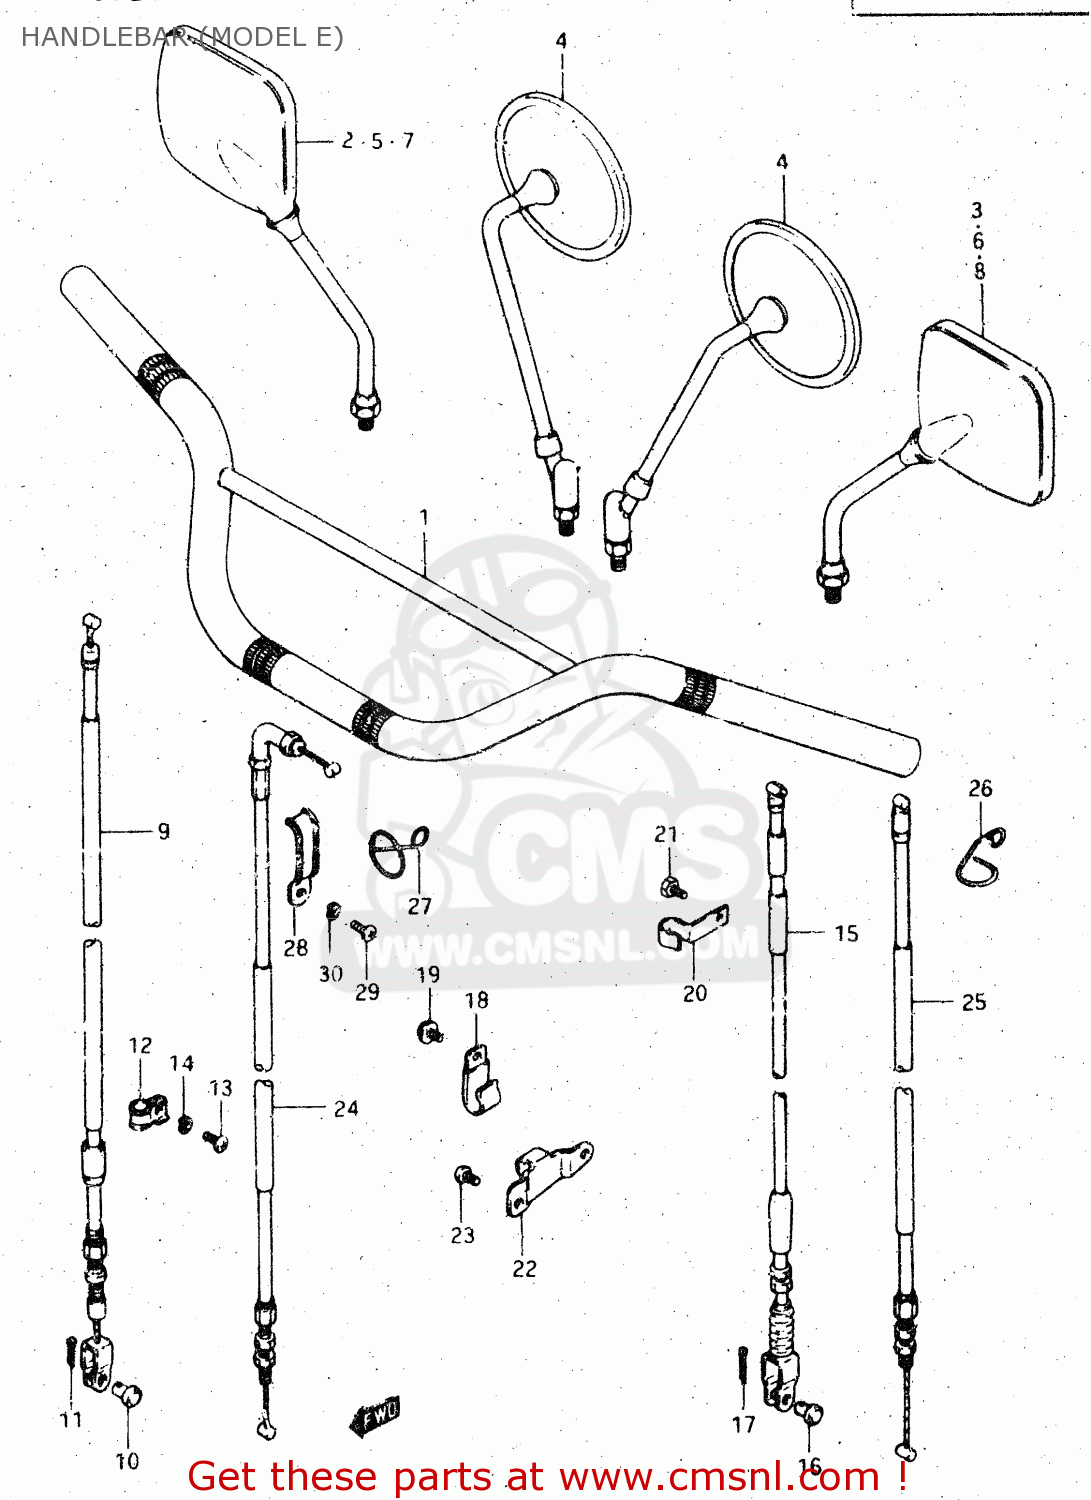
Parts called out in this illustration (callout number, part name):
1	HANDLEBAR (BLACK)
2	MIRROR ASSEMBLY,REAR VIEW
3	MIRROR ASSEMBLY,LEFT
4	MIRROR ASSY,RH
5	MIRROR ASSEMBLY,RIGHT
6	MIRROR ASSEMBLY,LEFT
7	MIRROR, REAR VIEW RH
8	MIRROR, REAR VIEW LH
9	CABLE ASSEMBLY,FRONT BRAKE
10	PIN(L:17.5)
11	PIN
12	GUIDE,CABLE
13	SCREW
14	LOCK WASHER
15	CABLE ASSEMBLY,CLUTCH
16	PIN(L:15)
17	PIN
18	CLAMP
19	SCREW
20	CLAMP,CLUTCH CABLE NO.1
21	BOLT
22	STOPPER,CLUTCH CABLE
23	SCREW
24	CABLE ASSY,THROTTLE
25	CABLE ASSY,DECOMP
26	GUIDE
27	GUIDE,CABLE
28	CLAMP
29	SCREW
30	LOCK WASHER
